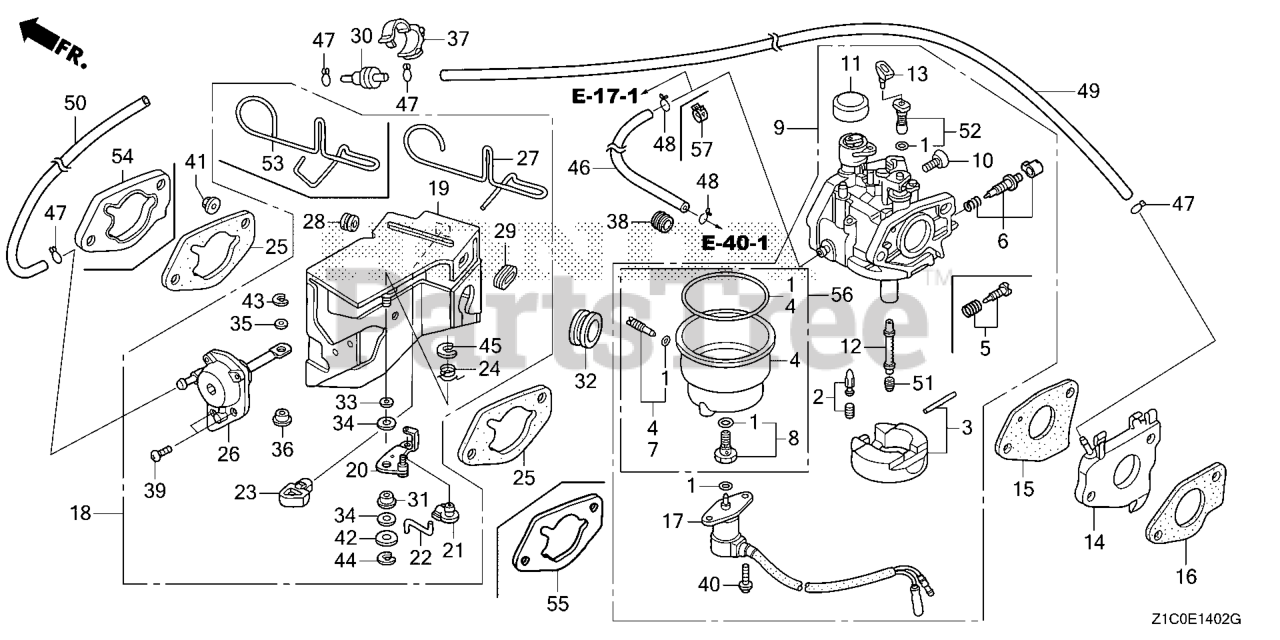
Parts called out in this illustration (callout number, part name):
1	GASKET SET
2	VALVE SET, FLOAT
3	FLOAT SET (CARBURETOR NO.)
4	CHAMBER SET, FLOAT
6	SCREW SET (CARBURETOR NO.)
7	SCREW SET, DRAIN (ADVENTURE GREEN) (CARBURETOR NO.)
9	CARBURETOR ASSY. (BEC1C A)
10	SCREW, THROTTLE STOP
11	CAP, CHOKE LEVER DUST
12	NOZZLE, MAIN
13	COLLAR, SET
14	INSULATOR, CARBURETOR
15	GASKET, CARBURETOR
16	GASKET, CARBURETOR INSULATOR
17	VALVE ASSY., SOLENOID
18	STAY ASSY., MANUAL CHOKE
19	STAY, SOLENOID
20	LEVER, CHOKE
21	JOINT, ROD
22	ROD, CHOKE
23	STOPPER, CHOKE ROD
24	SPRING, MANUAL CHOKE
26	DIAPHRAGM ASSY.
28	GROMMET, CHOKE ROD
29	GUIDE, CHOKE ROD
30	VALVE, DASHPOT CHECK
31	BUSH, ARM PIVOT
32	GROMMET, FENDER
33	WASHER, CHOKE LEVER
34	SEAL, CHOKE LEVER
35	WASHER, THRUST (2.7X8)
36	COLLAR, LEVER
39	SCREW, PAN (5X12)
40	SCREW-WASHER (5X12)
42	WASHER, PLAIN (5MM)
43	E-RING (2MM)
44	E-RING (4MM)
45	E-RING (7MM)
46	BULK HOSE, FUEL (4.5X3000) (Honda Code 5137104). (4.5X140)
47	CLIP, TUBE (B7)
48	CLIP, TUBE (B8)
49	BULK HOSE, VACUUM (3.5X8000) (3.5X130)
50	BULK HOSE, VACUUM (3.5X8000) (3.5X130)
51	JET, MAIN (#108) (CARBURETOR NO.)
51	JET, MAIN (#110) (CARBURETOR NO.)
51	JET, MAIN (#112)
52	JET SET, PILOT (#45) (CARBURETOR NO.)
53	ROD, CHOKE CONTROL
54	SPACER, CARBURETOR
55	GASKET, AIR CLEANER
